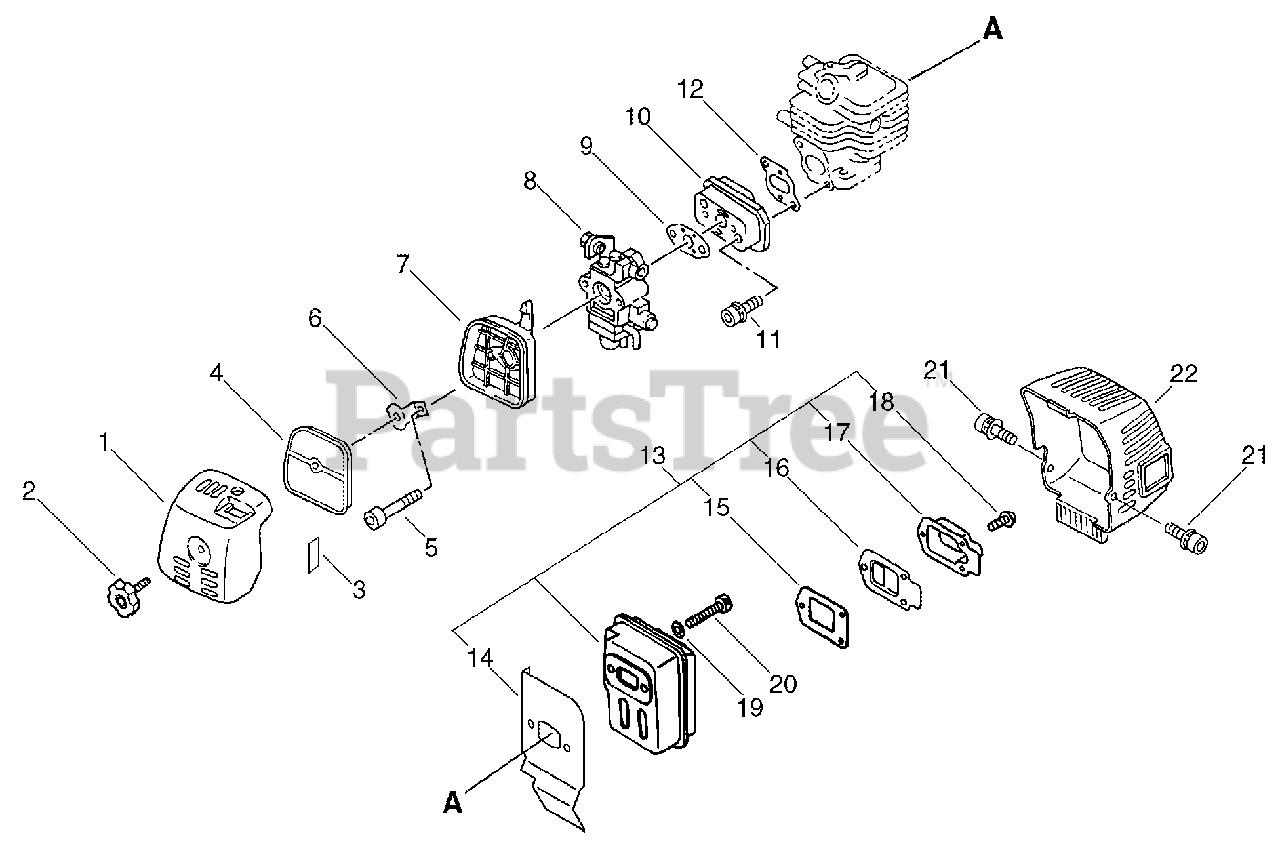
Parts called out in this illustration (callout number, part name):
1	COVER, AIR FILTER
2	THUMBSCREW
3	LABEL, CHOKE
4	FILTER, HEAVY-DUTY AIR
5	SCREW 5×55
6	PLATE, PREVENT
7	CASE, AIR FILTER
8	CARBURETOR - WYJ-192A
9	GASKET, CARBURETOR
10	INSULATOR, INTAKE
11	BOLT 5×25
12	GASKET, INTAKE
13	MUFFLER ASSY
14	HEAT SHIELD, EXHAUST
15	GASKET, EXHAUST
16	GUIDE, EXHAUST
17	OUTLET, EXHAUST
18	SCREW 4×10
19	WASHER, FLAT 5.5×10×0.8
20	BOLT 5×55
21	BOLT 5×12
22	COVER, MUFFLER
